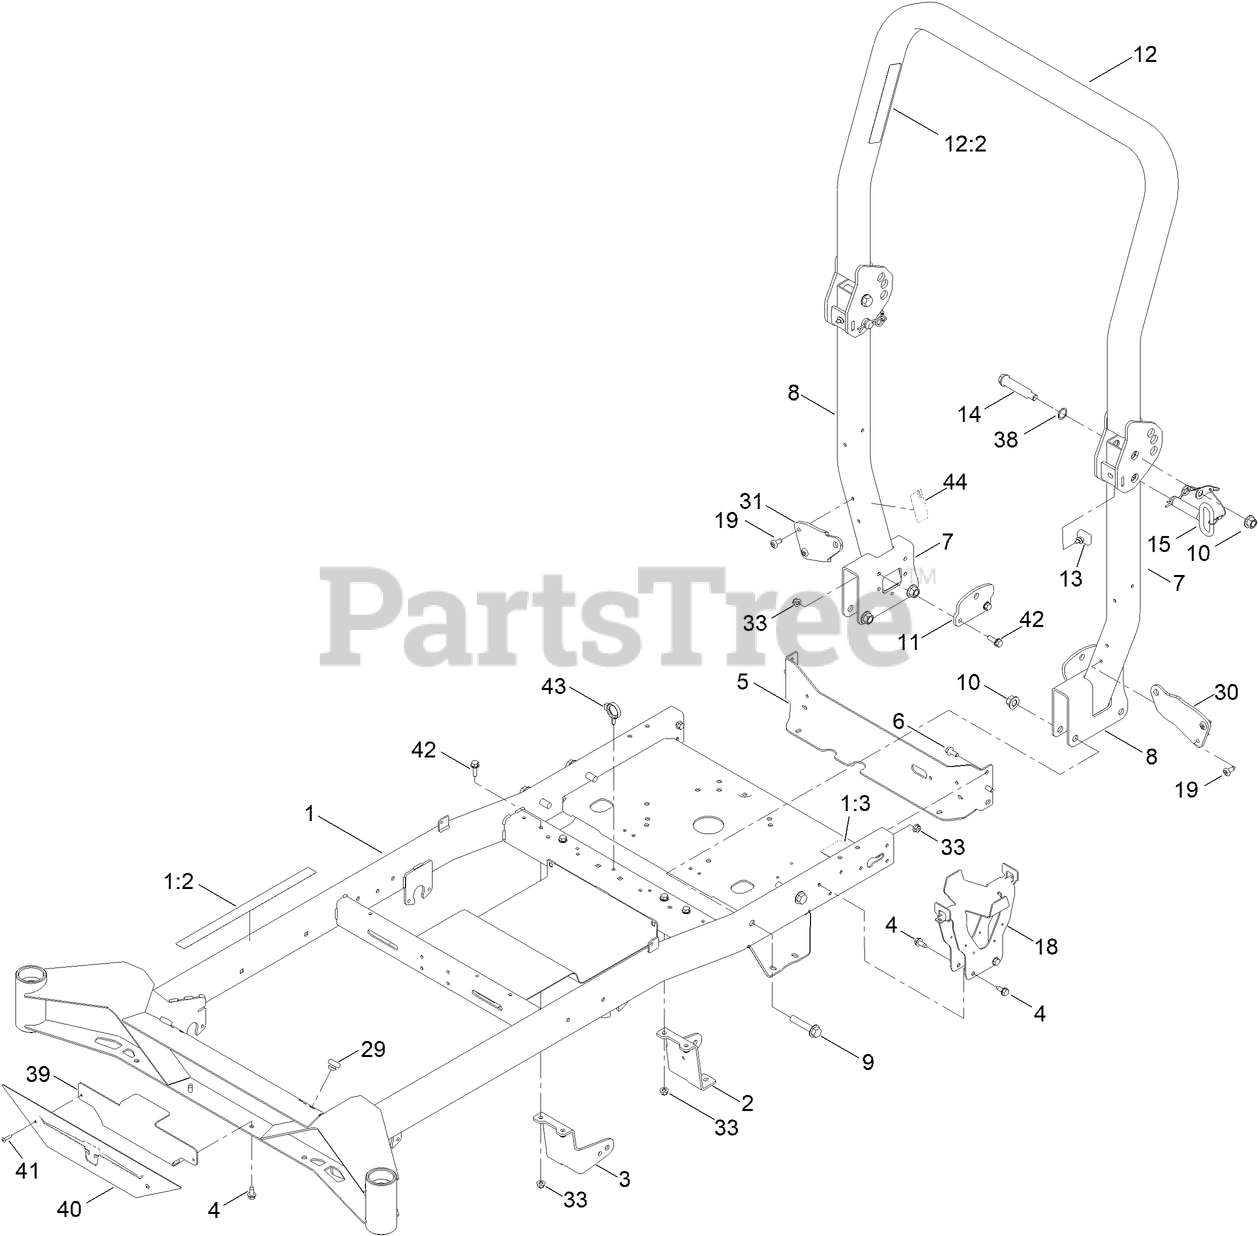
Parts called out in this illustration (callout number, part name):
1	FRAME W/DECALS ASM
1:2	DECAL-WARNING(AURORA)
1:3	DECAL-BYPASS
2	MOUNT-DRIVE, LH
3	MOUNT-DRIVE, RH
4	SCREW-HWHTF
5	PLATE-MOUNT, REAR
6	SCREW-HHF
7	RH ROPS ASM [BLACK]
8	LH ROPS ASM [BLACK]
9	SCREW-HHF
10	NUT-HF
11	PLATE-PIVOT, MYRIDE
12	TUBE-ROPS, UPPER ASM
12:2	DECAL-WARNING
13	BUMPER-ROPS
14	BOLT-SHOULDER
15	PIN-ROPS, ASM
18	TRAY-BATTERY
29	BUMPER-RUBBER
30	PLATE-SHOCK, LH
31	PLATE-SHOCK, RH
33	NUT-HF, NI
38	WASHER-WAVE
39	PLATE-BACKER
40	LOGO-PLATE-FRONT
41	RIVET-TRIFOLD
42	SCREW-HHF
43	CLAMP-HOSE
44	DECAL-COMPLIANCE, ROPS
